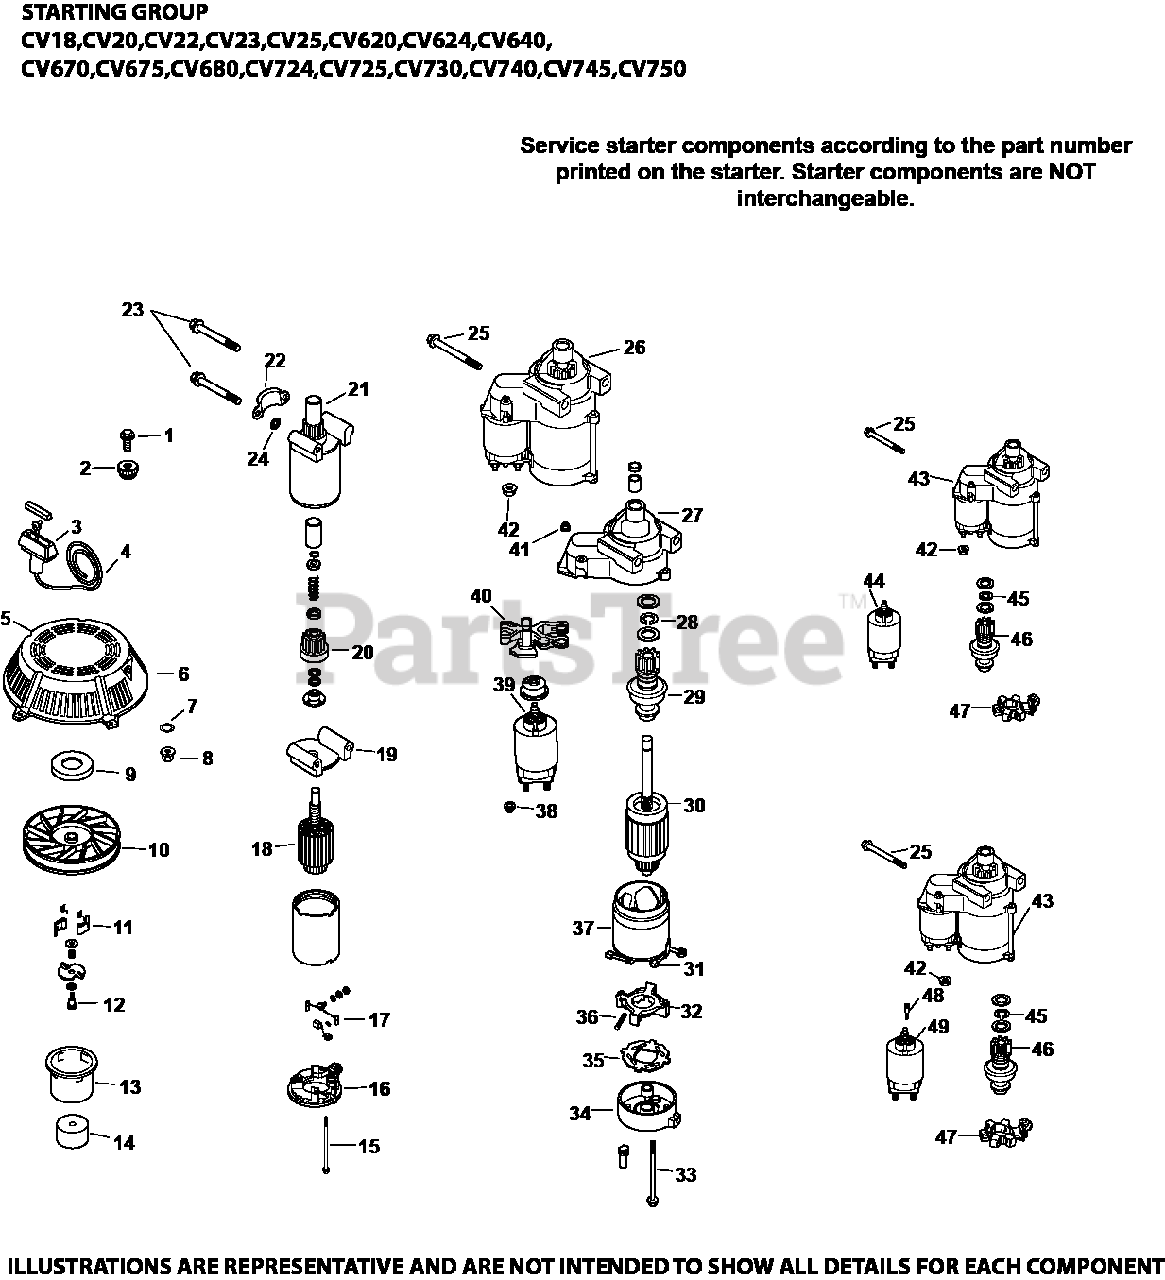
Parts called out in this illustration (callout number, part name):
25	SCREW, FLG M8X1.25X80
42	NUT, FLG M8X1.25
43	ELECTRIC STARTER - SOLENOID SHIFT USE 25 098 20-s
45	RING, RETAINING
46	KIT, STARTER PINION
47	KIT, BRUSH HOLDER
48	SCREW, EXTERNAL TORX HEAD
49	KIT, SOLENOID
